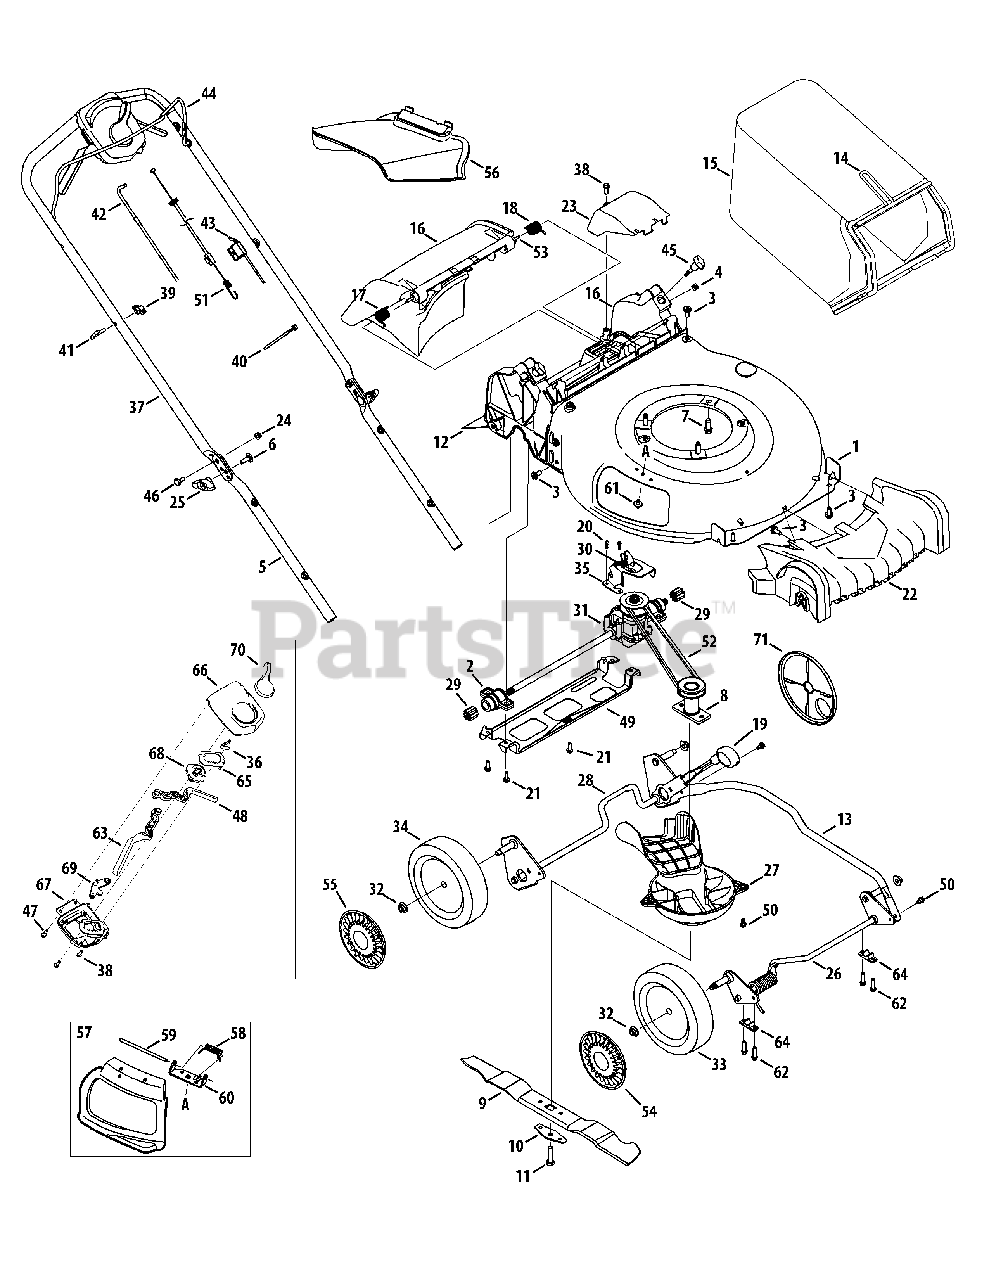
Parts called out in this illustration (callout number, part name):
1	Deck , 21"
2	Bearing Assembly
3	Screw, 5/16-14 x .750
4	Nut, Sq., 1/4-20
5	Lower Handle
6	Carriage Screw ,5/16-18
7	Screw, 3/8-16 x 1.00
8	Blade Adapter
9	Mulching Blade
10	Blade Bell Support
11	Screw, 3/8-24 x 1.50
12	Trailing Shield
14	Grass Catcher Frame
15	Grass Bag
16	Rear Discharge Door Assembly
17	Torsion Spring - RH
18	Torsion Spring - LH
19	Adjustment Lever Knob
20	Screw, .159 x .43 Hex Washer
21	Screw, 1/4-15 x 1.25
22	Front Cover
23	Transmission Cover
24	Nut, Flange Lock, 1/4-20
25	Wing Knob
26	Front Axle Assembly
27	Engine Baffle
28	Rear Axle Assembly
29	Spur Gear, 10T
30	Exten. Spring, 2.675
31	Transmission Assembly
32	Flange Lock Nut, 3/8-16
33	Front Wheel
34	Rear Wheel
35	Transmission Bracket
36	Spring
37	Upper Handle
38	Screw, 1/4-15 x .750
40	Cable Tie
41	Rope Guide
42	Drive Cable
43	Control Cable
44	Blade Control
45	Wing Nut
46	Sldr. Screw, .375 x .126 x 1/4-20
47	Scr., Shldr, 1/4-15 x .970
48	Control Lever LH
49	Rear Support Bracket
50	Scr., Shldr., 1/4-20 x .50
51	Speed Adjustment Cable
52	V-Belt
53	Pivot Rod
54	Hubcap, Grey
55	Hubcap, Grey
56	Side Discharge Chute
57	Mulch Plug (Incl. 58-60)
58	Torsion Spring
59	Hinge Pin
60	Chute Deflector Bracket
61	Screw, 1/4-20 x .500
62	Screw, 1/4-15 x 1.000
63	Control Lever RH
64	Bushing, Lock, .505 Dia. X .62
65	Cable Adjust Plate
66	Upper Housing
67	Lower Housing
68	Speed Adjust Actuator
69	Drive Cable Actuator
70	Speed Select Lever
71	Wheel Dust Cover
